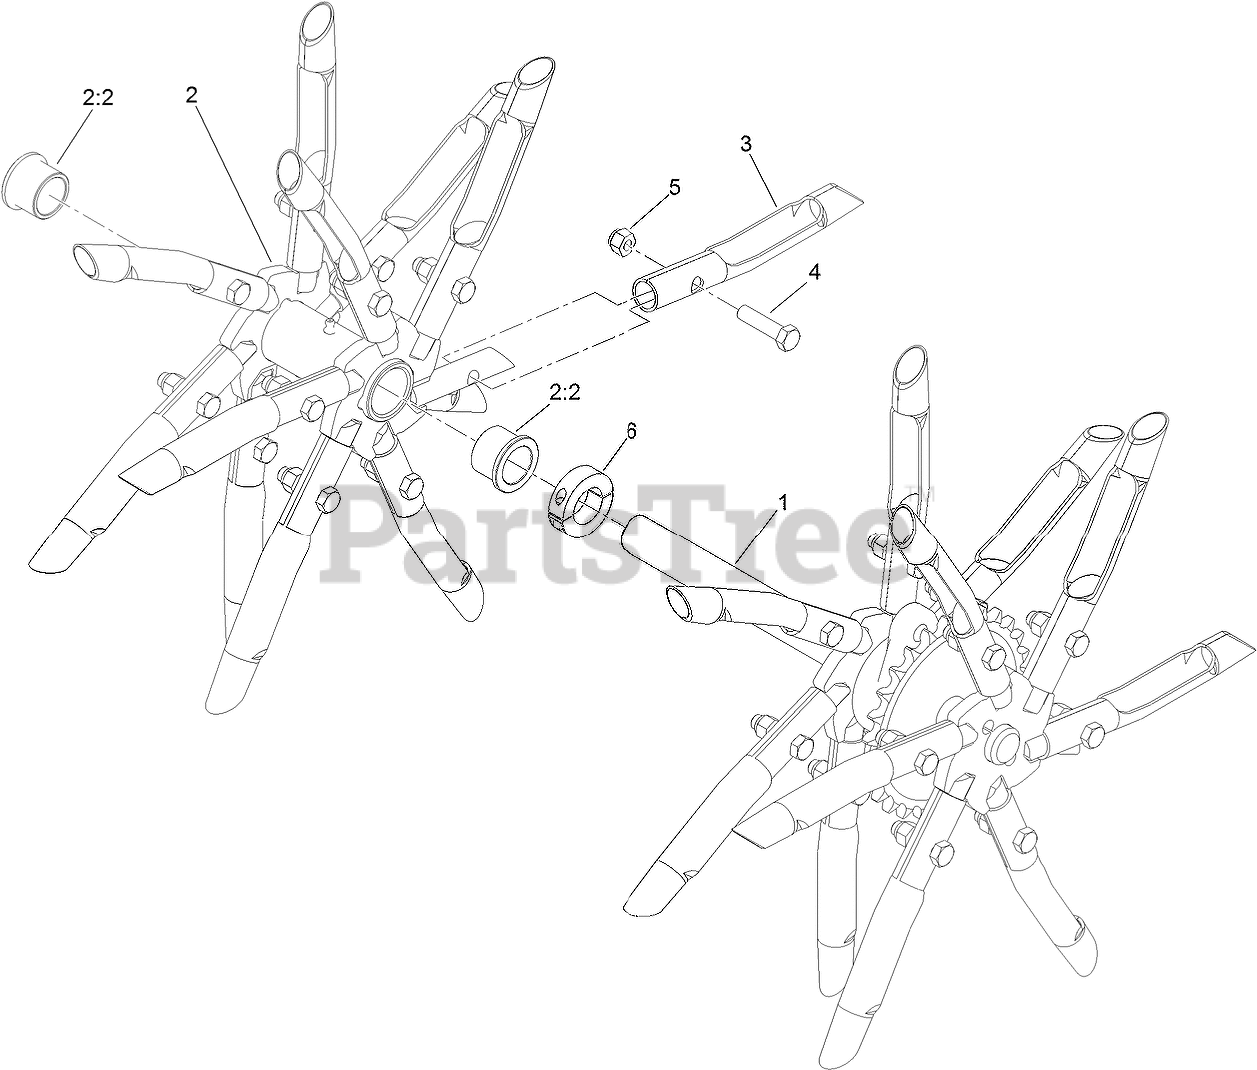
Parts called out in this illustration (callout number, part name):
1	TINE SHAFT- LH
2	ASM-FLOAT TINE SHAFT
2:2	BUSHING-FLANGE
3	TINE-CORING (3/4 INCH)
4	SCREW-HH
5	NUT-LOCK, NI
6	COLLAR-LOCKING
